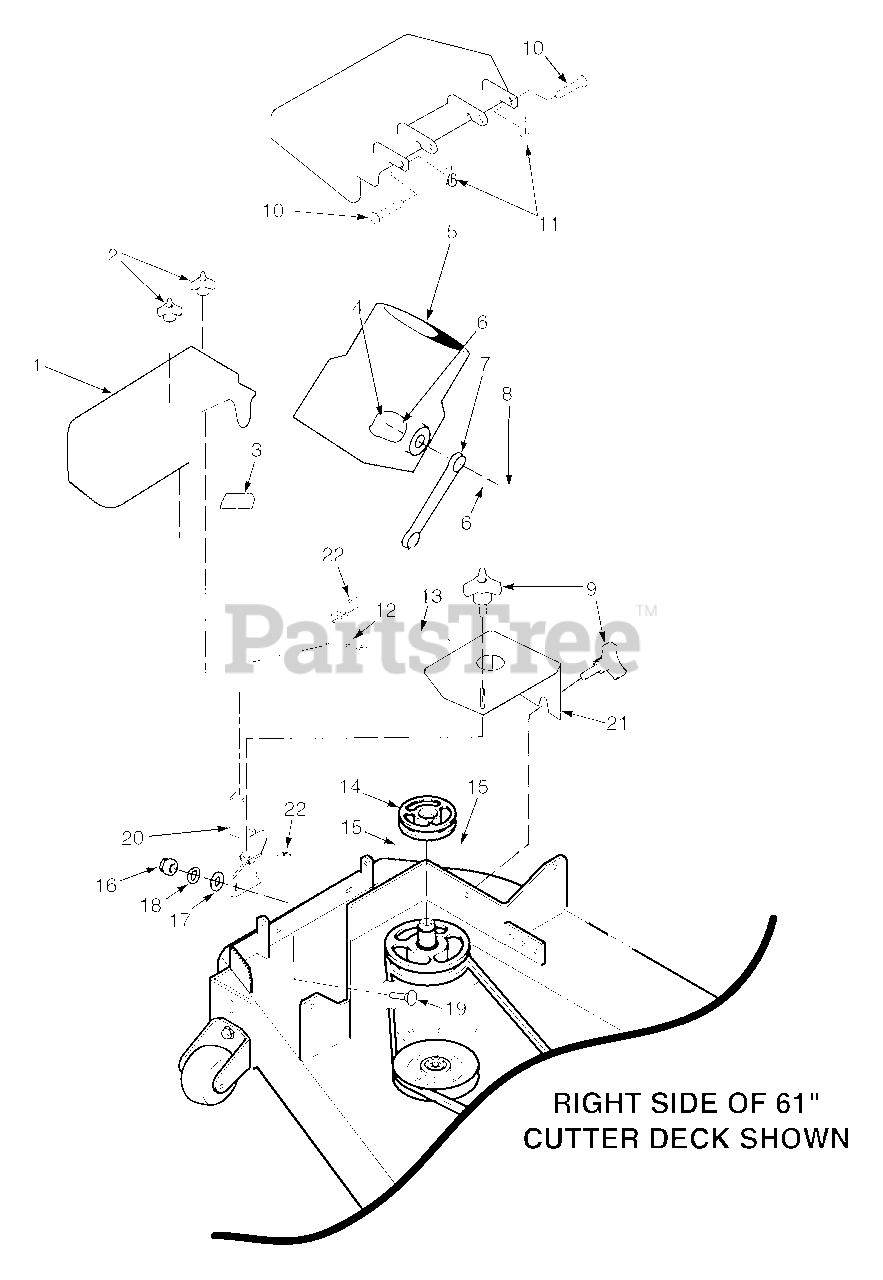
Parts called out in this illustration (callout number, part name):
1	Belt Cover, GC-STWC - 61"
2	Wingnut, Plastic 3/8 Small
3	Cap, Square Vinyl
4	Nut, Elastic Stop 1/4-20
5	Adapter, Blower GC-STT
6	Flatwasher, 1/4-.312 x .750 x .065
7	Rubber Strap 7-3/4"
8	Bolt, Hex Head 1/4-20 x 1-1/4"
9	Knob W/Stud, 3/8-16 x 1-1/4"
10	Clevis Pin, 5/16 x 1-1/2"
11	Pin, Rue Cotter 5/16 Dia.
12	Pin, Ring 1/2 x 2-1/4"
13	Lanyard
14	Pulley, 5-1/2" for 61" Deck
15	Setscrew, 5/16-18 x 3/8"
16	Nut, Elastic Stop 1/2-13
17	Lockwasher, 1/2"
18	Flatwasher, 1/2-.531 x 1.062 x .095
19	Bolt, Hex Head 1/2-13 x 1-1/2" Grade 5
20	Mounting Post Weldment, Blower - 61"
21	Belt Cover, GC-STWC-61
